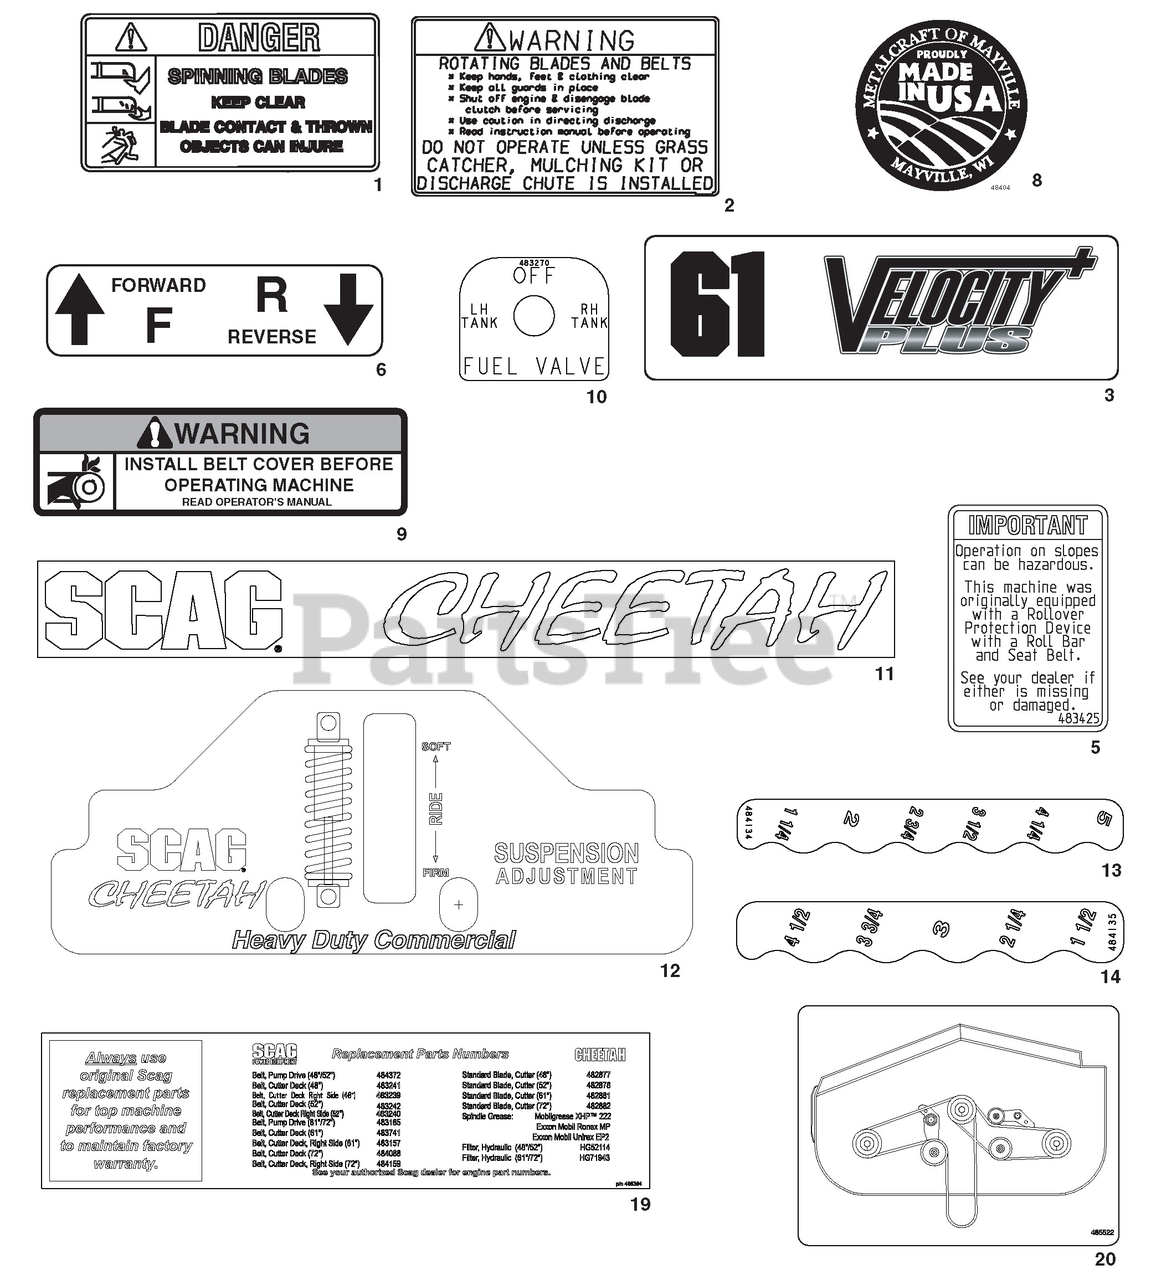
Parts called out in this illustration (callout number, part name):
1	Decal, Spinning Blades
2	Decal, Knives
3	Decal, 61" Velocity Plus
3	Decal, Velocity Plus - 61RD
3	Decal, 72" Velocity Plus
5	Decal, ROPS
6	Decal, Traction Control
8	Decal, Made in USA
9	Decal, Belt Cover
10	Decal, Fuel Shut Off
11	Decal, Scag Cheetah
12	Decal, Suspension Adjustment
13	Decal, Deck Height - LH
14	Decal, Deck Height - RH
19	Decal, SCZ Belt Routing
